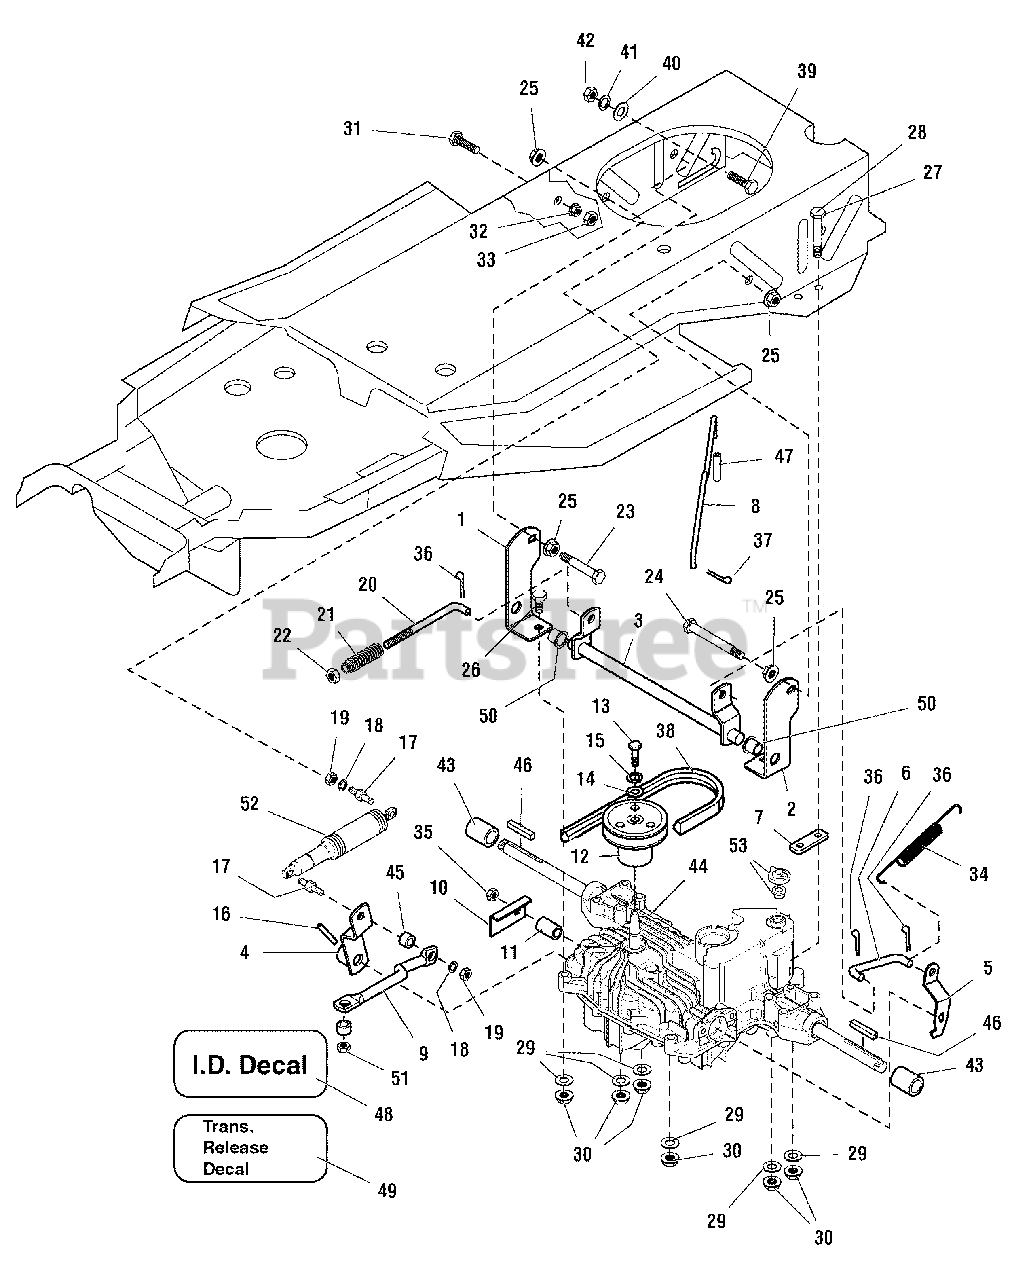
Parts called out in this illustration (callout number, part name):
1	STRAP, Torque - RH
2	STRAP, Torque - LH
3	CROSS SHAFT ASSEMBLY
4	CONTROL ARM ASSEMBLY
6	LINK, Brake
7	SPACER, Transmission
8	ROD, Dump Valve
9	ROD, Control
12	PULLEY ASSEMBLY
13	CAPSCREW, M06 X 1.00 X 30
14	WASHER, 1/4
15	LOCKWASHER, 1/4
16	PIN, Spring
17	STUD 5/16-18 X 57/64
18	LOCKWASHER, 5/16
19	NUT, Hex, 5/16-18
21	SPRING, Brake
22	NUT, Nylock, 3/8-16
23	CAPSCREW, 5/16-18 X 2-3/4
24	CAPSCREW, 5/16-18 X 5-1/2
25	NUT, Whiz Flange Lock, 5/16-18
26	CAPSCREW, 5/16-18 X 1.50
27	CAPSCREW 5/16-18 X 2.75
28	CAPSCREW 5/16-18 X 3.25
29	WASHER, 5/16
30	NUT, Flange Lock, 5/16-18
31	CAPSCREW, 5/16-18 X 1
32	NUT, Whiz Flange Lock, 5/16-18
33	NUT, Center Lock, 5/16-18
34	SPRING
35	NUT, Center Lock Jam, 3/8-16
36	PIN, Cotter, 3/32 - 3/4
37	PIN, Cotter, 1/16 - 3/4
39	CARRIAGE BOLT, 1/4-20 X 1/2
40	WASHER, 1/4
41	LOCKWASHER 1/4
42	NUT, Hex, 1/4-20
43	SPACER, Axle
44	TRANSMISSION ASSEMBLY, Tuff Troq K56
46	KEY
48	DECAL, Serial Plate Addendum
49	DECAL, Transmission Release
51	NUT, Nylock, 5/16-18
52	SHOCK ABSORBER
53	VENT ASSEMBLY
